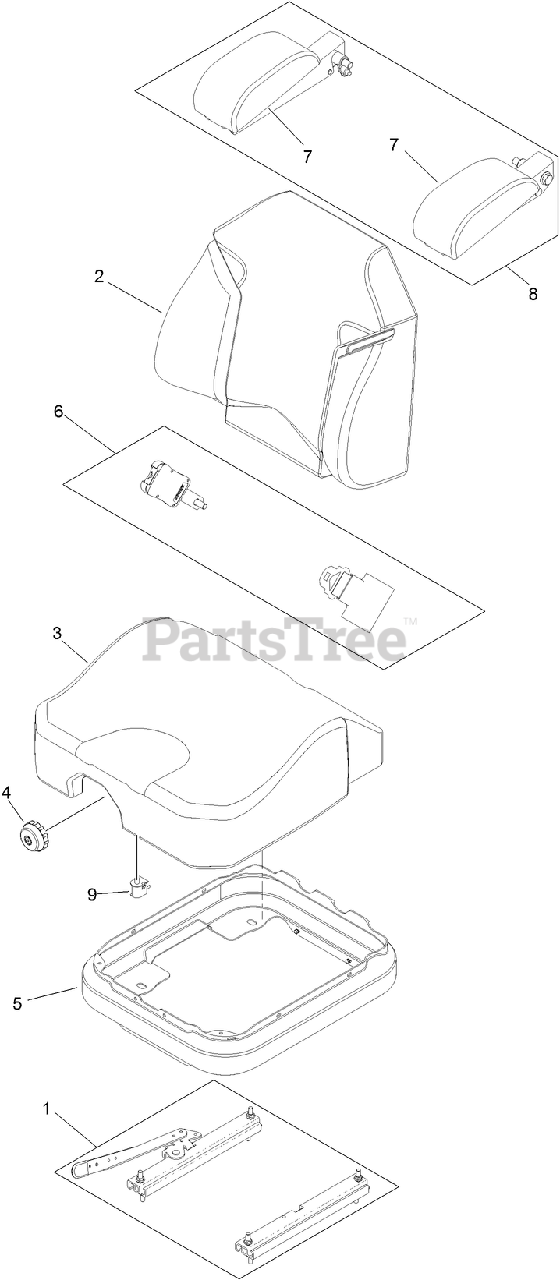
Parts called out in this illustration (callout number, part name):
1	SEAT TRACK SET
2	COVER-BACK
3	COVER-CUSHION
4	KNOB-ADJUSTER
5	Cover-Suspension Bellows
6	SEAT BELT SERVICE KIT
7	ARM REST PAD SET
8	ARM REST SET
9	SWITCH-BAIL
